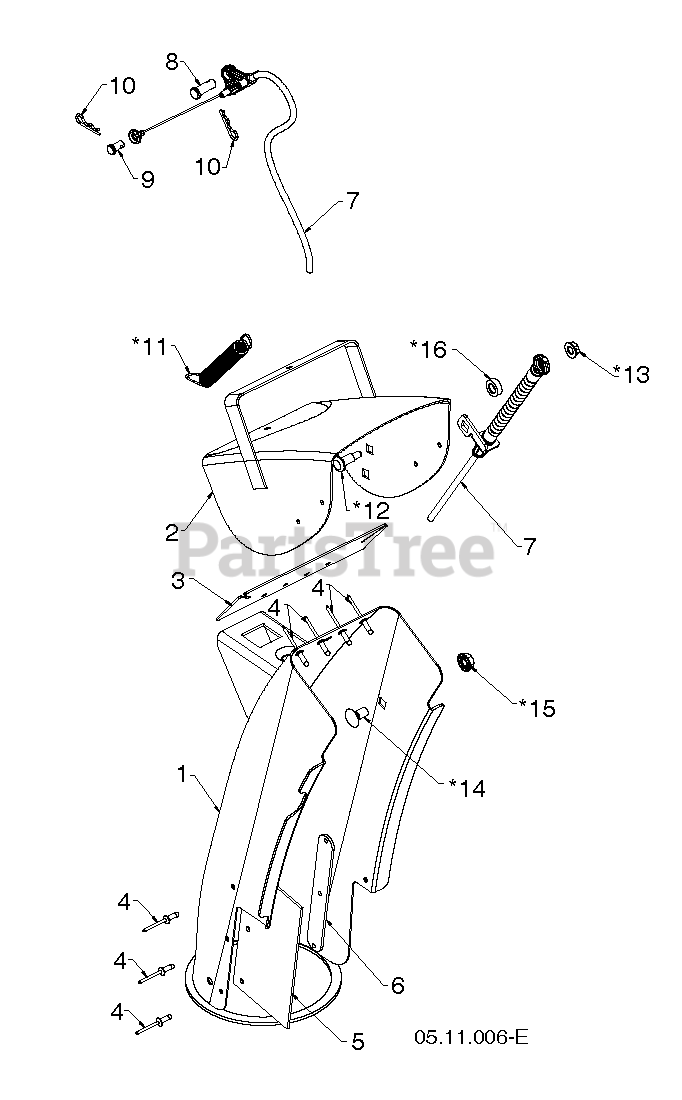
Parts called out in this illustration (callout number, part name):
1	ASM.CHUTE/DEFLECTOR.668
7	CABLE CONTROL.CHUTE.DEFL.BOWDE
8	PIN CLEVIS 5/16X.875
9	PIN CLEVIS .25 X .31
10	HAIRPIN.SOFT.ZINC.059X1.125
11	SPRING.DEFLECTOR.REM.CHUTE
12	BOLT.CARR.W.3125 SHLDR..25-20
13	NUT.HEX.LRG.FLANGE.1/4-20.LOCK
14	BOLT CAR BLK 5/16-18 X 5/8
15	LOCKNUT-FLANGE 5/16-18
16	WASHER.NYLON.326 X.625 X.205
